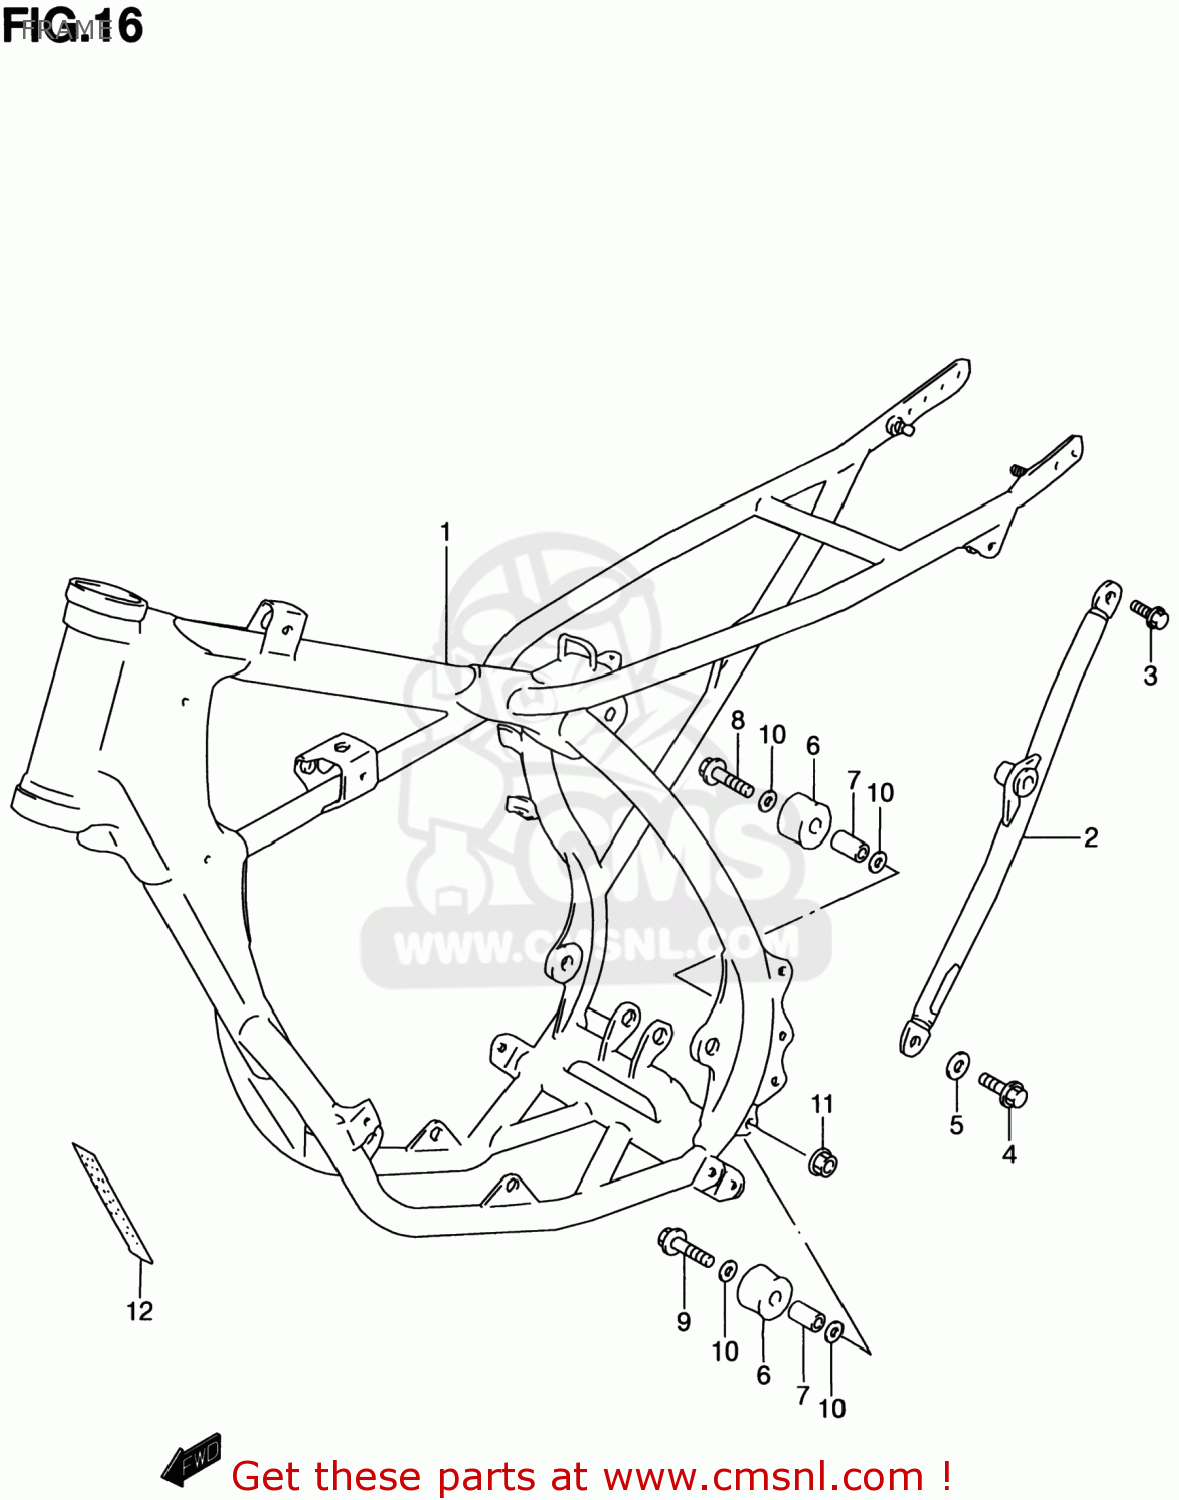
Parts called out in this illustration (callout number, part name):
1	FRAME COMP
2	TUBE,FRAME SIDE(CHARCOAL)
3	BOLT(8X22)
4	BOLT(8X16)
5	WASHER
6	ROLLER,CHAIN CONTROL
7	SPACER(8.6X12.2X25.5)
8	BOLT(8X38)
9	BOLT
10	SHIM(8X16X1)
11	NUT
12	PLATE,WARNING
